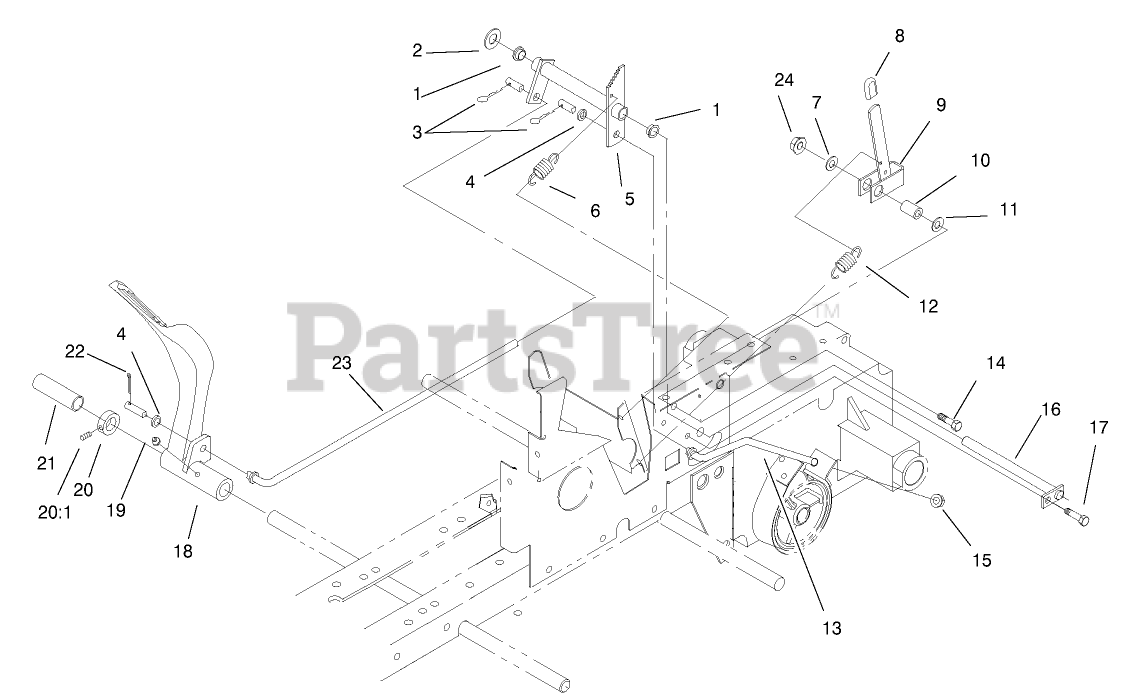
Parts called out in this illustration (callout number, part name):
1	BUSHING-FLANGED
2	WASHER-FLAT
3	PIN-HAIR
4	WASHER-NYLON
5	BELCRANK ASM
6	SPRING-EXTENSION
7	WASHER-FLAT
8	GRIP
9	BRAKE LEVER ASM
10	SPACER
11	WASHER-FLAT
12	SPRING-BRAKE
13	ROD-REAR BRAKE
14	SCREW-HH
15	NUT-LOCK, NI
16	ROD ASM
17	SCREW-HWHTF
18	PEDAL-BRAKE, GEAR
19	FITTING-GREASE
20	COLLAR
20:1	SCREW-HSH
21	SLEEVE-PROTECTIVE
22	PIN-COTTER
23	ROD-BRAKE
24	NUT-LOCK, NI
